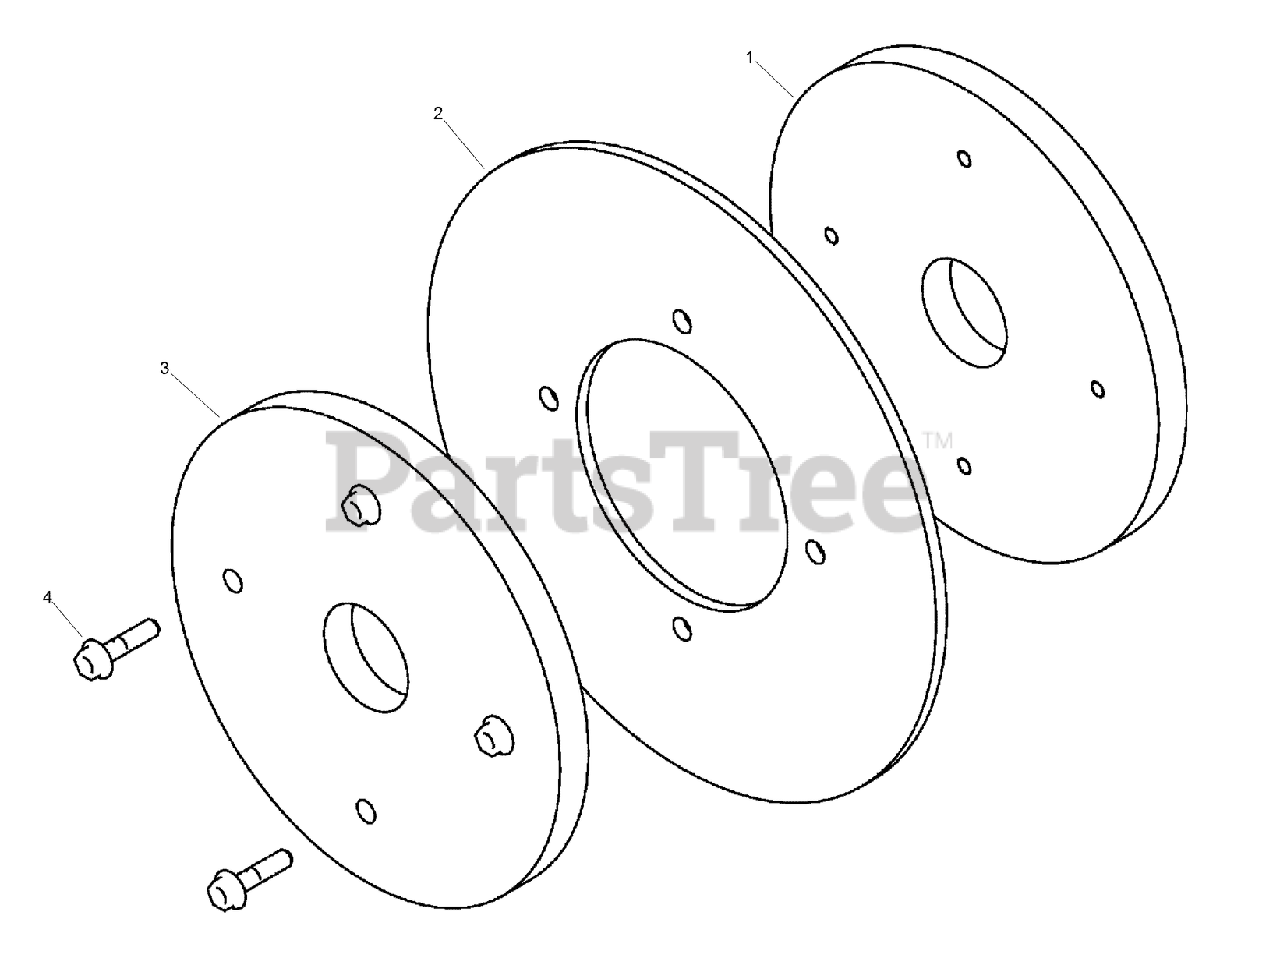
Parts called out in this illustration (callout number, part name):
2	SEAL-RUBBER, FOLLOWER
3	PLATE
4	SPRING
